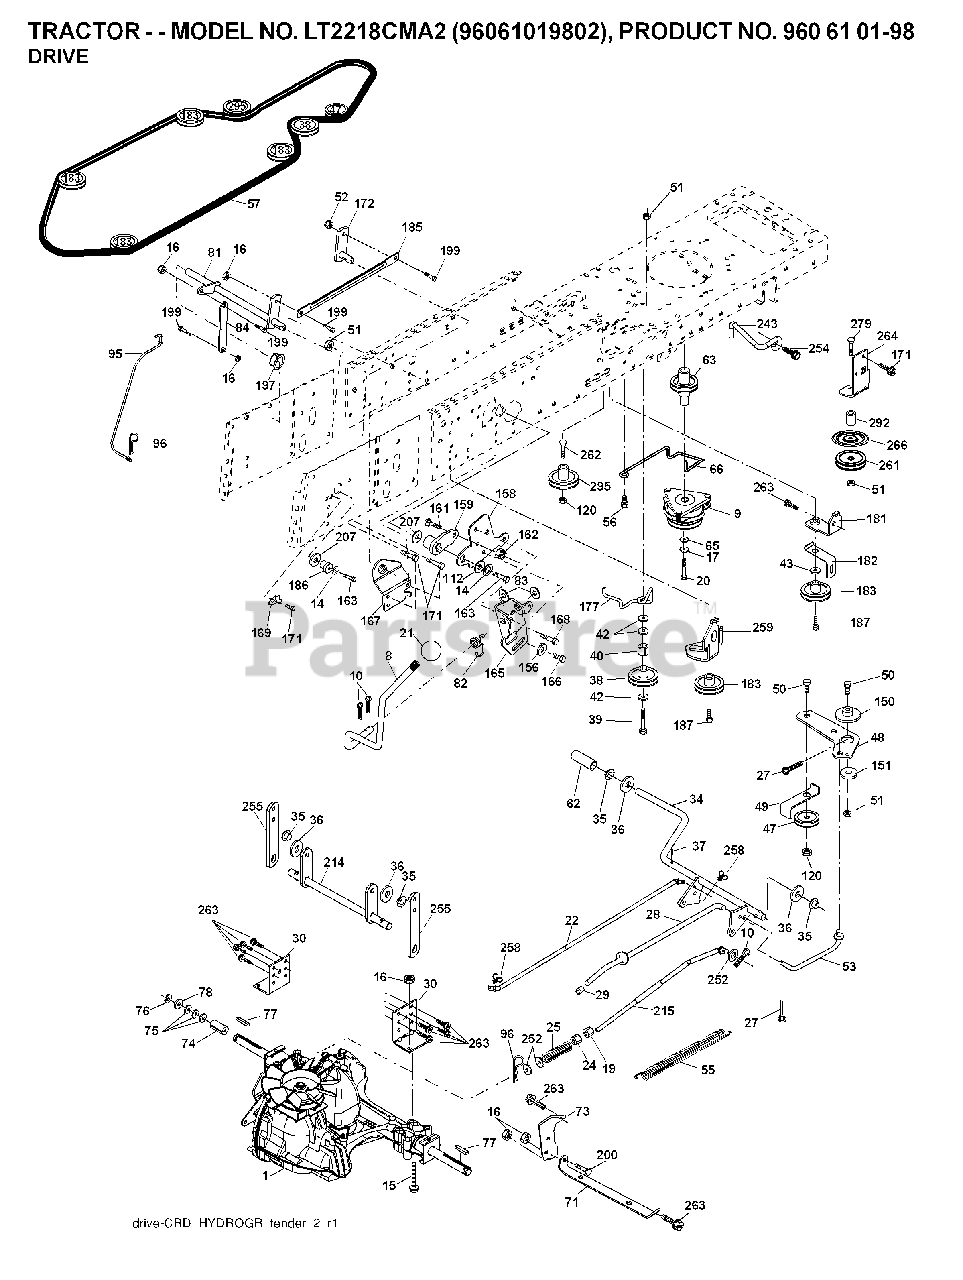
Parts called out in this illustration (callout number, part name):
8	ROD SHIFT FENDER ADJUST LT
10	PIN COTTER
14	LOCKWASHER
15	BOLT HEX 5/16-18 GR 5
16	NUT.71038.31-18.HEX.NYLOCK
19	NUT
20	BOLT HEX 7/16-20X4-1/4"
21	PISTOL KNOB
24	NUT
27	COTTER PIN
28	ROD, PARKING BRAKE
29	PLUNGER CAP
30	BRKT, TRNSXLE MNT 20"
34	SHAFT, FOOT PEDAL
35	BEARING.NYLON
36	WASHER LT
37	DRIVE PIN
38	PULLEY.FLAT
42	WASHER
43	WASHER T
47	IDLER PULLEY
48	BELLCRANK, CLUTCH
49	RETAIN BELT
50	BOLT.3/8-16X1.50
51	LOCKNUT
52	LOCKNUT
53	LINK.CLUTCH.7.66.2005
55	SPRING, RETURN LT
56	SCREW.3/8-16
62	PEDAL COVER T
65	LOCKWASHER
66	KEEPER BELT ENGINE
71	STRAP TORQUE LH HYDRO
73	STRAP TORQUE RH HYDRO
74	SPACER AXLE
76	E-RING LT
77	SQUARE KEY
81	SHAFT ASSY
82	SHIFT SPRING
83	WASHER
96	RETAINER M
112	WASHER LT
120	NUT LOCK FLG 3/8-16 UNC
150	BUSHING.BELLCRANK.GRD.DR
151	WASHER 12/32X2X10GA
156	WASHER.SRRTD.5/16
158	BRACKET
159	HUB.SHIFT
161	BOLT
162	NUT.CROWNLOCK.1/4
163	BOLT
165	RP BRACKET
166	SCREW
167	BRACKET
168	BOLT.SHOULDER.5/16-18X
169	PLATE.FASTENING.CROSS.SHAFT
171	SCREW LT
187	BOLT.5/16-18X1.25
197	NYLINER SNAP 5/8" ID
199	BOLT SHOULDER 5/16-18 UNC
200	BOLT
207	WASHER NYL
243	BRACKET, ANTI-ROTATION
254	SCREW 3/8-16X1
258	CLIP RETAINER
261	FLAT IDLER PULLEY
263	SCREW, 3/8-16X3/4
279	BOLT
295	PULLEY IDLER COMPOSITE
